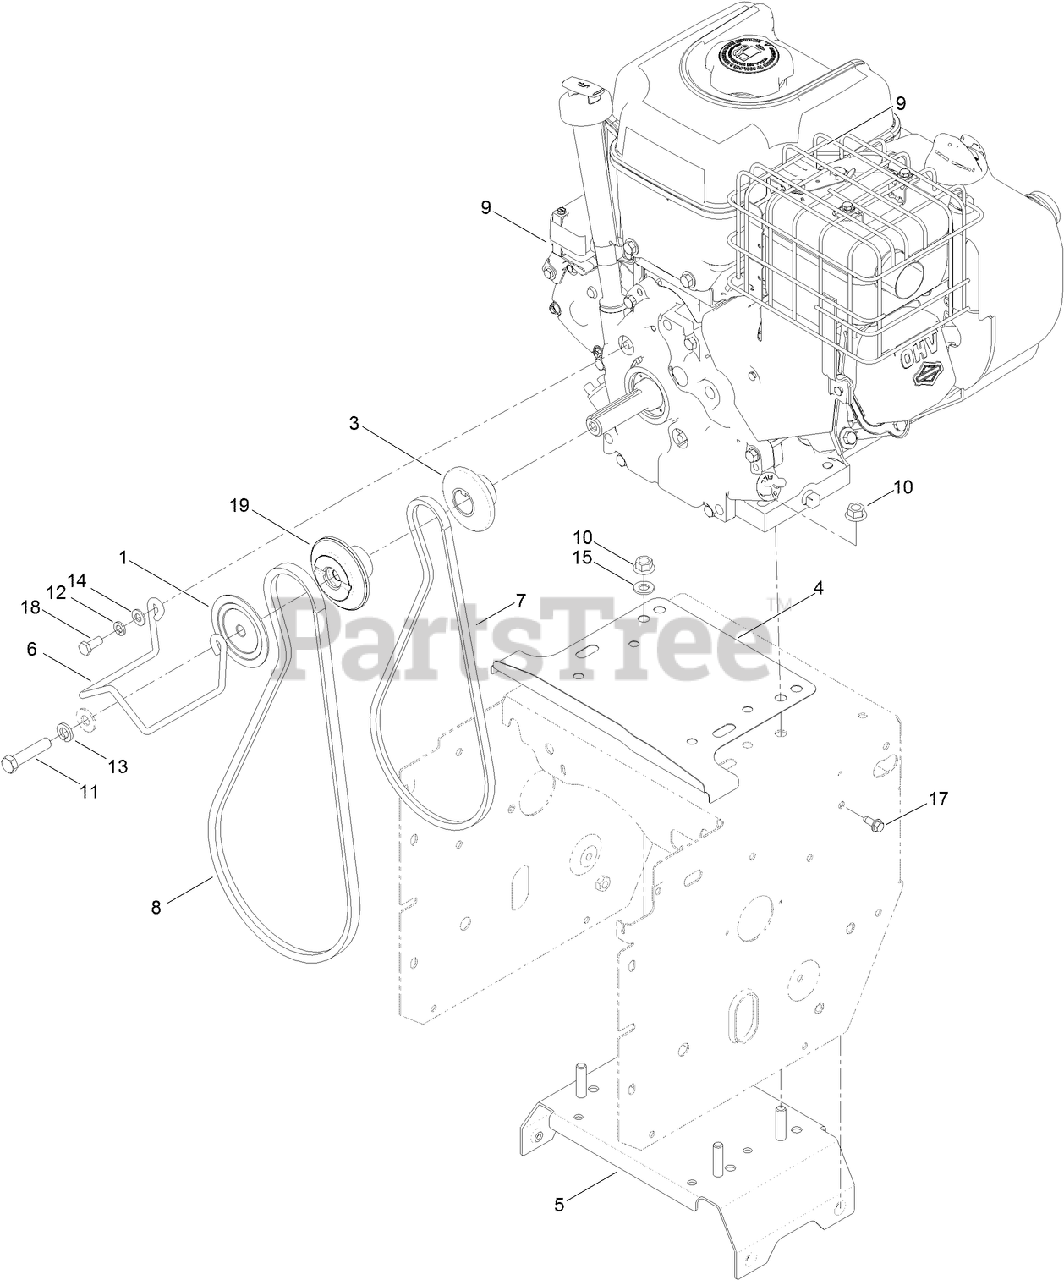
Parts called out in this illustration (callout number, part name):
1	SHEAVE-HALF, IMPELLER
3	SHEAVE-HALF, TRACTION
4	SHIELD-DRIVE
5	FRAME BRACE ASM
7	V BELT-TRACTION
8	BELT-V
10	NUT-HF
11	SCREW-HH
12	WASHER-LOCK
13	WASHER-LOCK
14	WASHER-PLAIN
15	WASHER-FLAT
17	SCREW-HWH
18	SCREW-HH
19	PULLEY-ENGINE, CENTER
